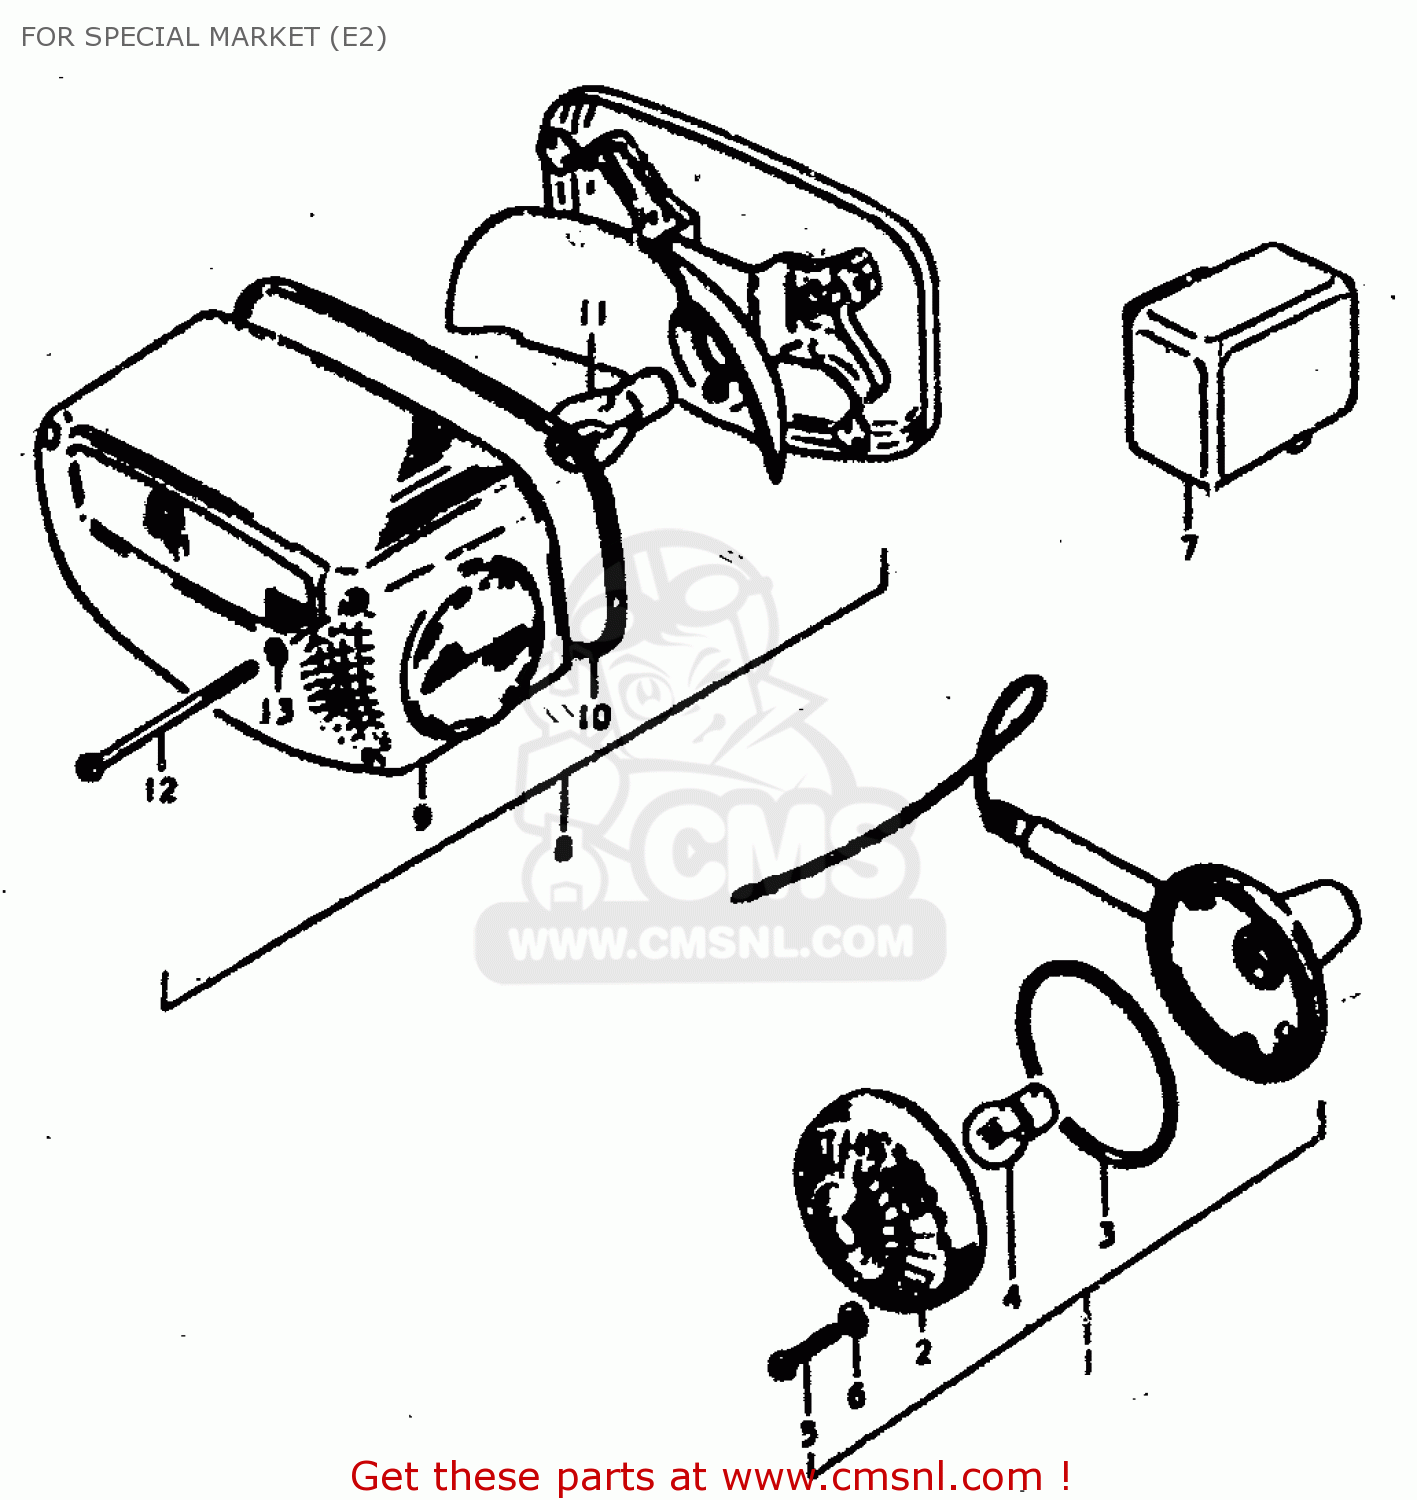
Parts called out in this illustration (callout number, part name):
1	LAMP ASSY, REAR TURN SIGNAL
2	LENS
3	GASKET (NAS)
4	BULB 12V 21W
5	SCREW
6	GASKET (NAS)
8	LAMP ASSY, REAL COMBINATION
9	LENS,REAR COMBINATION LAMP
10	GASKET (NAS)
11	BULB
12	SCREW (4X55)
13	GASKET (NAS)
